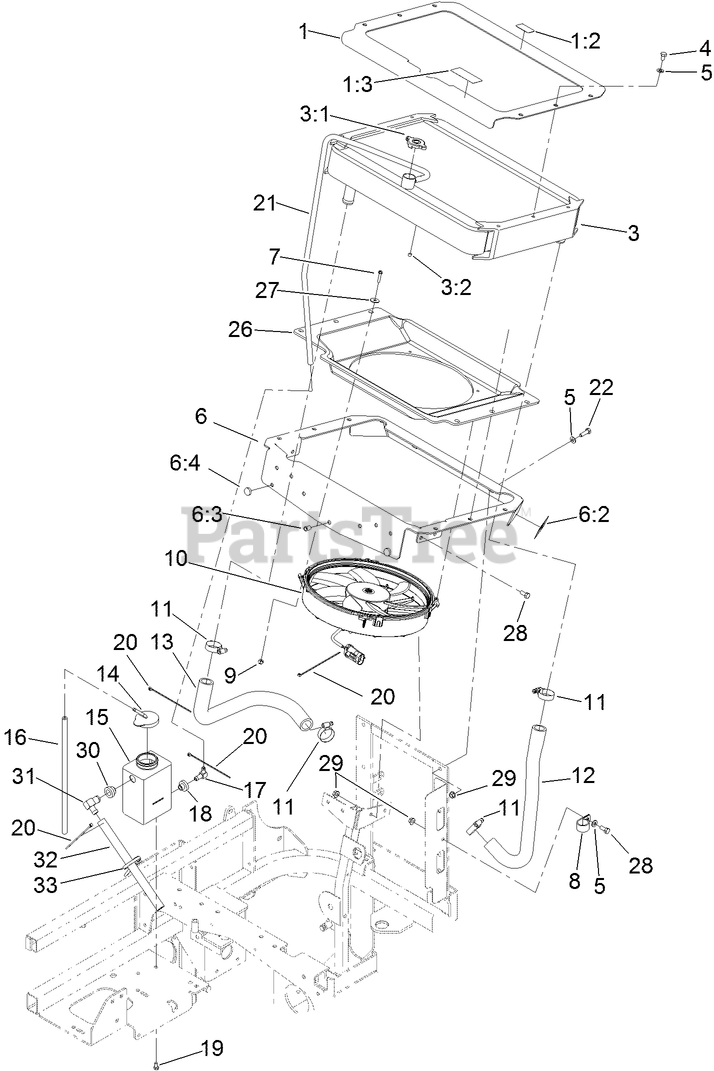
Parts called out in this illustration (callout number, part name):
1	TOP RADIATOR PLATE ASM
1:2	DECAL-SURFACE, HOT
1:3	DECAL-ANTIFREEZE
3	RADIATOR ASM
3:1	CAP-RADIATOR
3:2	PLUG-PIPE
4	SCREW-HH
5	WASHER-PLAIN
6	BOTTOM RAD PLATE ASM
6:2	DECAL-FAN, RADIATOR
6:3	INSERT-NUT
6:4	BUMPER
8	CLIP-LOOM
9	NUT-LOCK, HH
10	FAN-HI PERFORMANCE
11	CLAMP-HOSE
12	HOSE-RADIATOR, LH
13	HOSE-RADIATOR, RH
14	CAP-TANK, OVERFLOW
15	TANK-OVERFLOW
16	HOSE-LINE, FUEL
17	FITTING-ELBOW
18	BUSHING-VALVE, FUEL
19	SCREW-HH
20	TIE-CABLE
21	HOSE-OVERFLOW
22	SCREW-HH
26	SHROUD
27	WASHER
28	SCREW-HH
29	NUT-HF
30	BUSHING
31	FITTING-ELBOW
32	HOSE-OVERFLOW
33	TIE-PLASTIC
